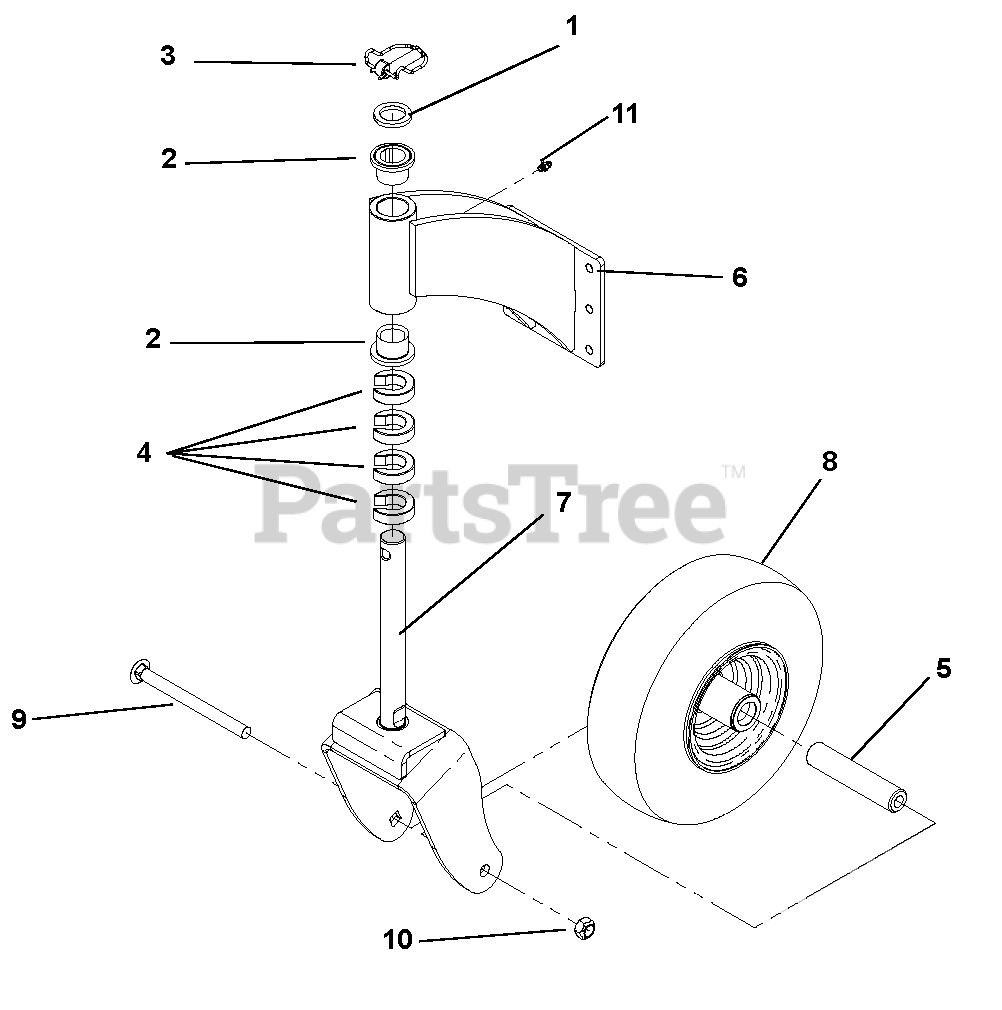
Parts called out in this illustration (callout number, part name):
1	BUSHING, 1.03X1.501.179
2	BRG, FLG 1.00X1.25X1.00
3	PIN, LOCK .438 X 2.00
4	C-SPACER, 1.00X1.77X.50
5	TUBE, 1.00X.50X4.76
6	WLDT, CASTER MOUNT ARIENS 52
7	WLDT, FR WHEEL FORK ARIENS 52
8	WHEEL, FRONT 11X4X5
9	BOLT, 1/2-13X6.00 CRG Y
10	LOCKNUT, 1/2-13 CROWN Y
11	GREASE ZERK, 1/4-28 STR .69 LG
